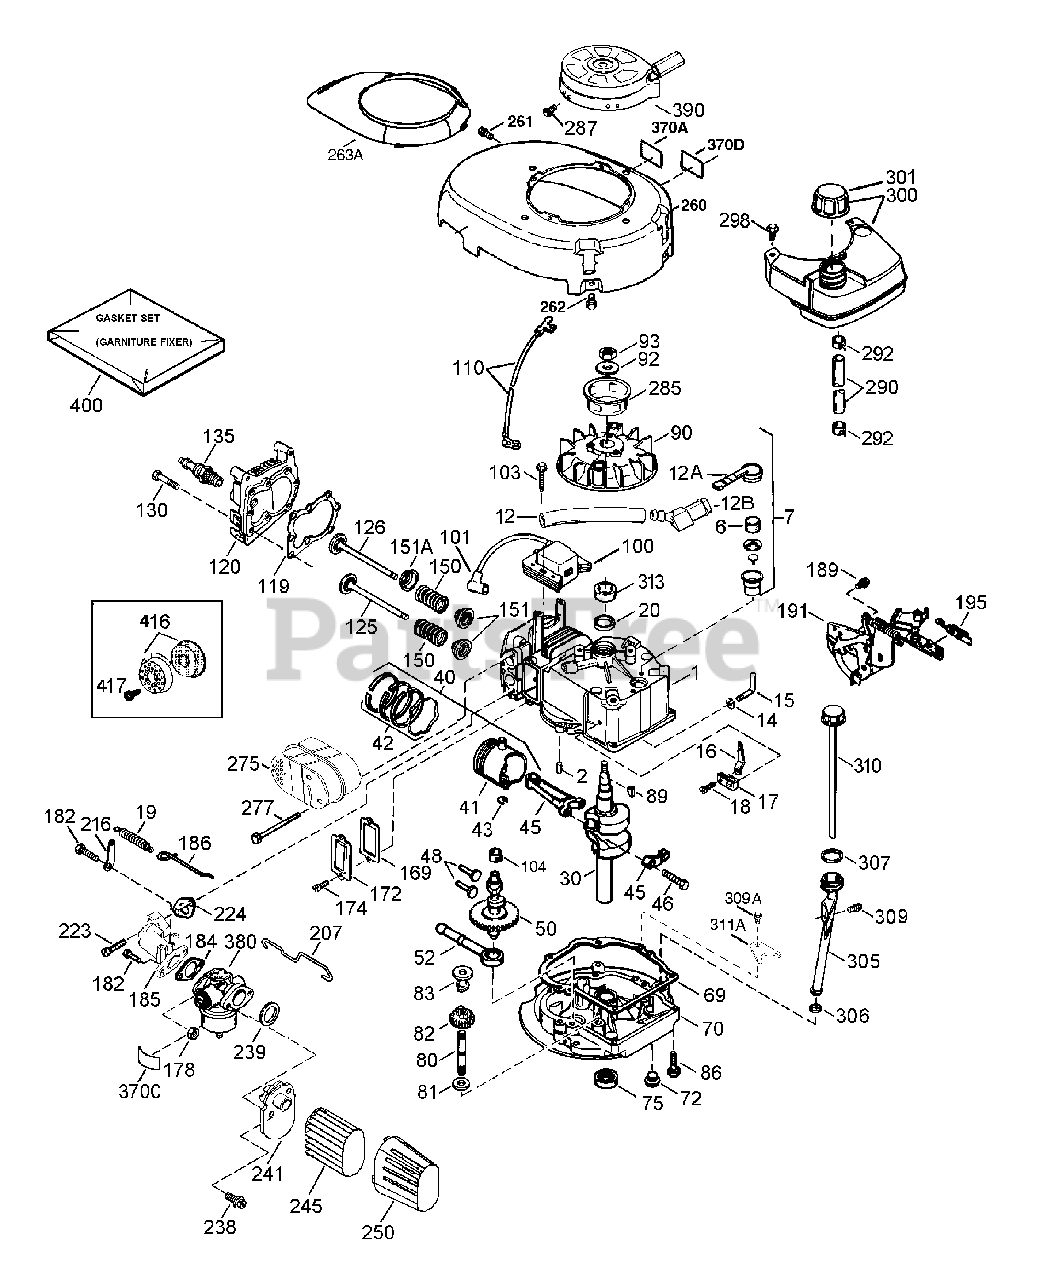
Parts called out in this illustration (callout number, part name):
1	Cylinder (Incl. 2, 20 & 150)
2	Dowel Pin
6	Breather Element
7	Breather Ass'y. (Incl. 6 & 12A)
12	Breather Tube
12A	Breather Cover & Tube (Incl. 12B)
12B	Breather Tube Elbow
14	Washer
15	Governor Rod (Incl. 14)
16	Governor Lever
17	Governor Lever Clamp
18	Screw, T-15, 8-32 x 19/64"
19	Extension Spring
20	Oil Seal
30	Crankshaft
40	Piston, Pin & Ring Set (Std.)
41	Piston & Pin Ass'y. (Std.)(Incl. 43)
42	Ring Set (Std.)
43	Piston Pin Retaining Ring
45	Connecting Rod Ass'y. (Incl. 46)
46	Connecting Rod Bolt
48	Valve Lifter
50	Camshaft (Exhaust)(MCR)(Incl. 104)
52	Oil Pump Ass'y.
69	Mounting Flange Gasket
70	Mounting Flange (Incl.72 thru 83)
72	Oil Drain Plug
75	Oil Seal
80	Governor Shaft
81	Washer
82	Governor Gear Ass'y. (Incl. 81)
83	Governor Spool
86	Screw, 1/4-20 x 1-1/4"
89	Flywheel Key
90	Flywheel
92	Belleville Washer
93	Flywheel Nut
100	Solid State Ignition
101	Spark Plug Cover
103	Screw, T-15, 10-24 x15/16"
104	Cam Bushing
110	Ground Wire
119	Cylinder Head Gasket
120	Cylinder Head
125	Exhaust Valve (1/32" OS)(Incl. 151)
125	Exhaust Valve (Std.)(Incl. 151)
126	Intake Valve (Std.)(Incl. 151 & 151A)
130	Screw, 5/16-18x1-7/16"
135	Resistor Spark Plug (RJ19LM)
150	Valve Spring
151	Valve Spring Cap
151A	Intake Valve Seal
169	Valve Cover Gasket
172	Valve Cover
174	Screw, 10-24 x 9/16"
178	Nut & Lock Washer, 1/4-28
182	Screw, 1/4-28 x 7/8"
184	Carburetor To Intake Pipe Gasket
185	Intake Pipe
186	Governor Link
189	Screw, 1/4-20 x 27/64"
191	S.E. Brake Bracket (Incl. 195)
195	Terminal
207	Throttle Link
216	R.P.M. Adjusting Lever
223	Screw, 1/4-20 x 1"
224	Intake Pipe Gasket
238	Screw, 10-32 x 49/64"
239	Air Cleaner Gasket
241	Air Cleaner Collar
245	Air Cleaner Filter
250	Air Cleaner Cover
260	Blower Housing
261	Screw, 10-24 x 9/16"
262	Screw, 1/4-20 x 1/2"
263A	Starter Grille
275	Muffler
277	Screw, 1/4-20 x 2-9/32"
285	Starter Cup
287	Screw, 8-32 x 21/64"
290	Fuel Line (6.75")
292	Fuel Line Clamp
298	Screw, 10-32 x 35/64"
300	Fuel Tank (Incl. 292 & 301)
301	Fuel Cap Ass'y
305	Oil Fill Tube (Incl. 306)
306	"O"-Ring
307	"O"-Ring
309	Screw, 10-32 x 1/2"
309A	Screw, 10-24 x 3/4"
310	Dipstick
311A	Hold Down Bracket
